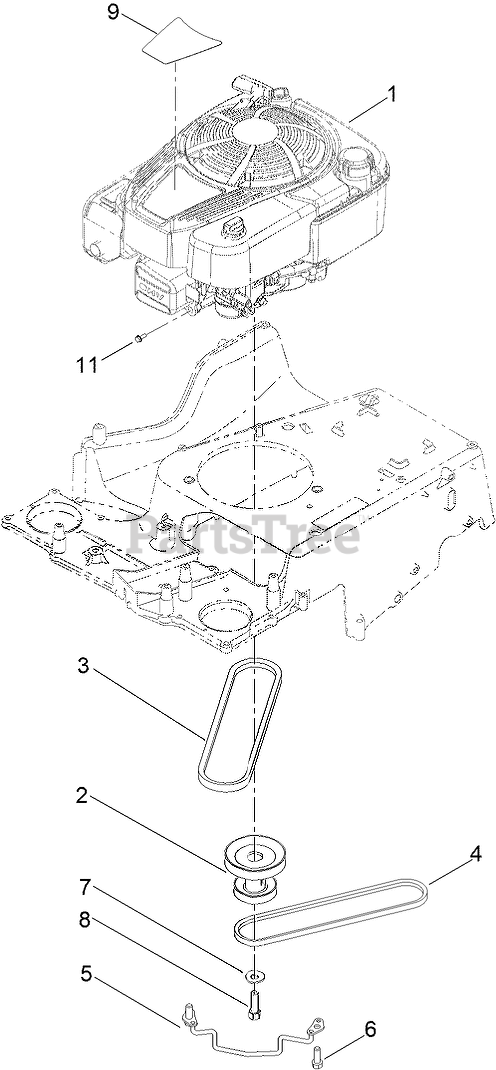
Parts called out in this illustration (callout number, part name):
2	PULLEY-ENGINE
3	V-BELT
4	V-BELT, TRACTION
5	GUIDE-BELT
6	SCREW-TAPTITE
7	WASHER-BELLEVILLE
8	SCREW-HH
9	DECAL-SHROUD
11	SCREW-TAPTITE
